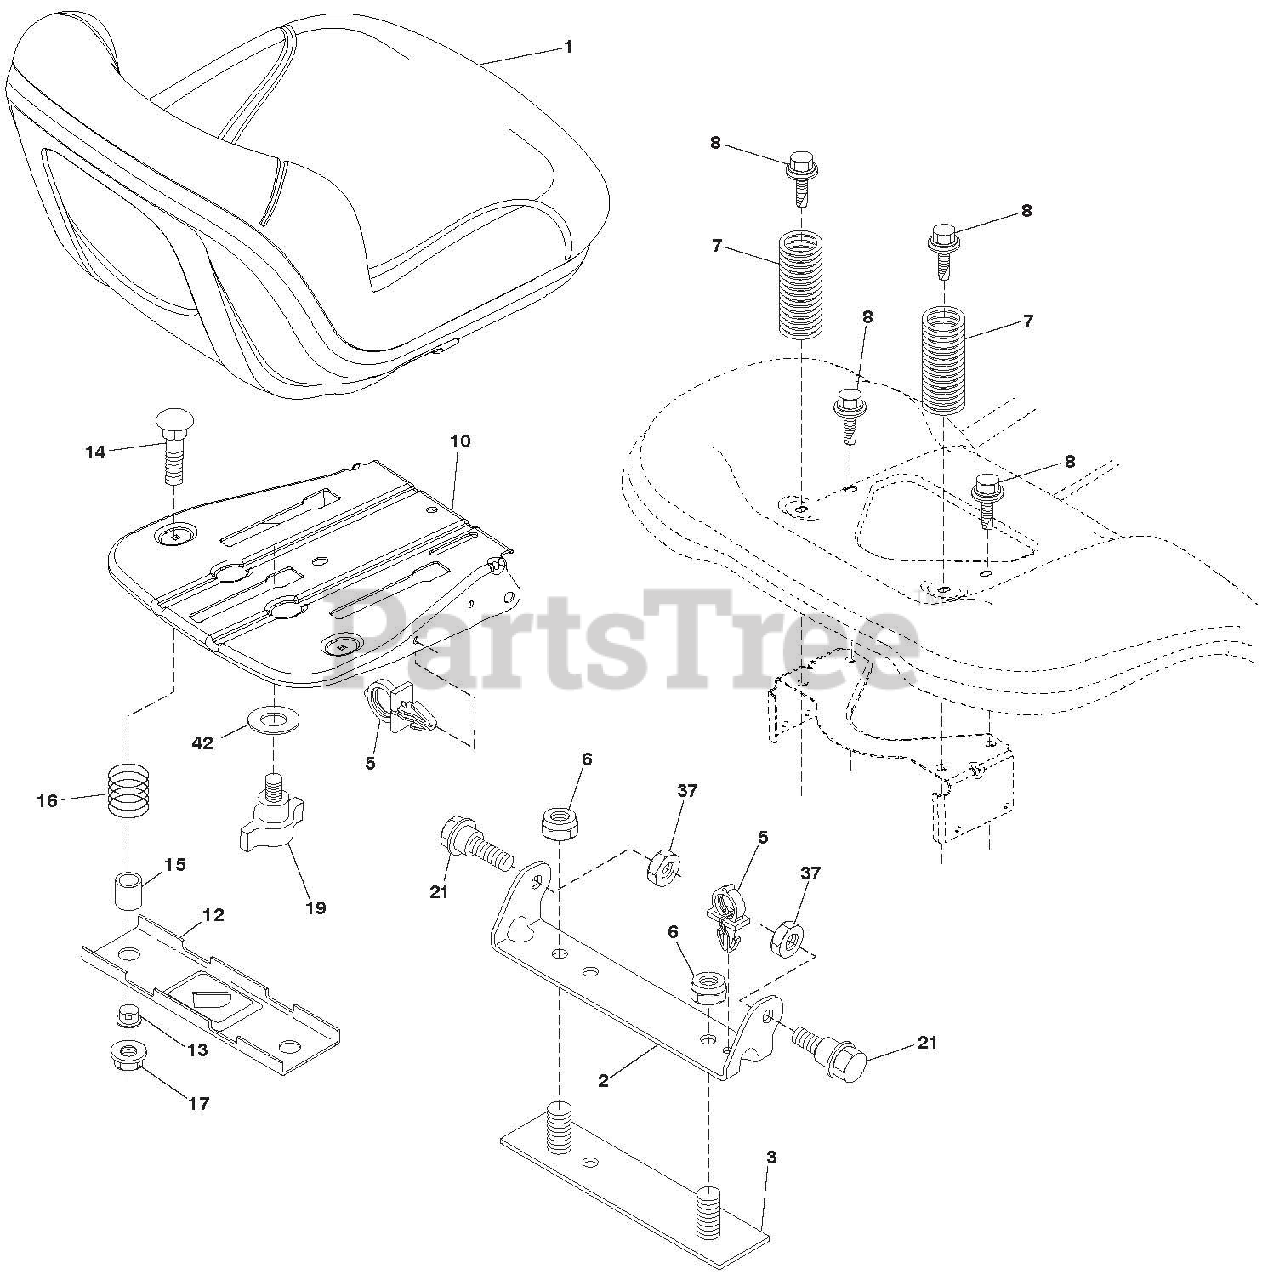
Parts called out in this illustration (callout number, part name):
1	SEAT.TA110.BLACK.ARIENS
2	BRACKET.PIVOT.FENDER.2002
3	STRAP ASM.FENDER.94
5	CLIP.PUSH-IN.HINGED
6	Locknut, Washer Insert 3/8-16
7	SPRING.SEAT.CPRSN.2.250.BLK.ZI
8	BOLT.5/16-18UNCX3/4 W/SEMS.BLK
10	PAN, SEAT
13	BUSHING.SNAP.BLK.NYL..50 ID.
14	BOLT.RDHD.SHT.NK.1/4-20X1-1/2
15	SPACER.SPLIT..28X.96.YEL.ZINC
16	SPRING.CPRSN.PLATE.SW.1.310.GA
17	NUT.LOCK.1/4 LGE.FLG.GR.5.ZINC
19	KNOB.SEAT ADJ.3/8-16"TEX
21	BOLT.SHLD.5/16-18 UNC-2A.BLK D
37	Locknut, Washer Insert 5/16-18
42	WASHER.CUP.SEAT.TEX LT
